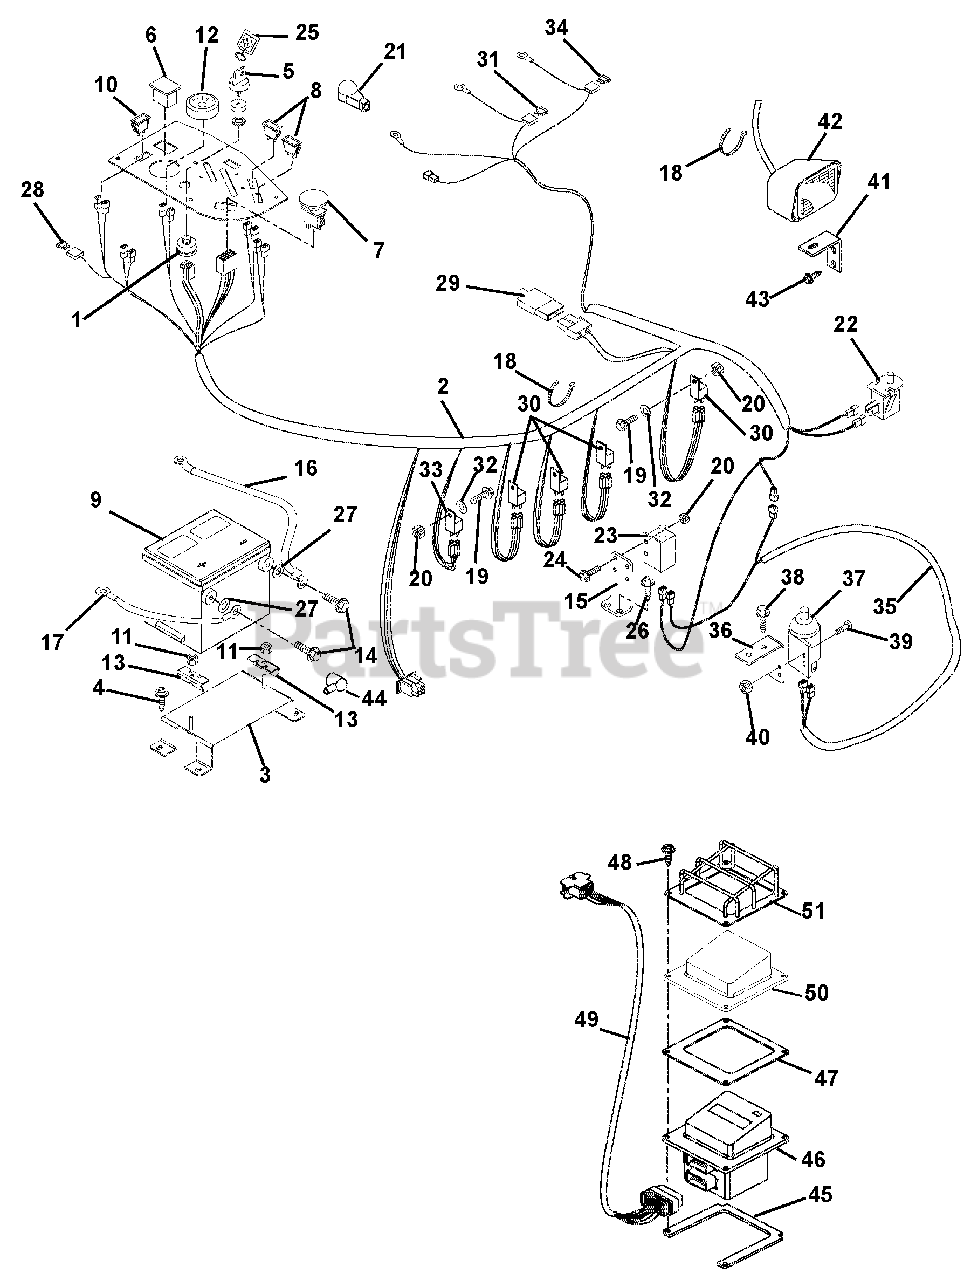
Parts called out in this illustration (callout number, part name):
1	Switch, Ignition (Diesel)
2	Harness, Wiring (Diesel)
3	Weldment, Battery Support
4	Screw-Tapping .38-16 x .75 Hex Washer Head
5	Key-with Cap
7	Switch-Clutch With Retainer Ring
8	Light-Indicator Kit
9	Battery with Tube
10	Switch, Light
11	Nut-Locking-Top-Flange .31-18
12	Gauge, Temperature
13	Bracket, Battery Hold-Down
14	Bolt-Hex .25-20 x .75 Grade 5
15	Mount, Safety Switch
16	Positive Cable
17	Cable, Negative Battery
18	Cable Tie
19	Screw-Machine 10-24 x .75 Hex Washer Head
20	Nut-Locking-Nylon 10-24 With Insert
21	Eyelet Terminal Boot
22	Switch, Snap Mounting (N.O.) (Included with Seat)
23	Switch-Single Pole
24	Screw-Machine 10-24 x .75 Hex Washer Head
25	Key Chain
26	Screw-Tapping .25-20 x .50 Hex Washer Head
27	Washer-Flat-Steel .406 x 1.00 x ..083
28	Fuse, 15 Amp
29	Diode, Connector Shell
30	Relay (Included with Harness)
31	Fuse, 30 Amp (Included with Harness)
32	Washer-Flat-Steel .25 x .562 x .049
34	Fuse, 50 AMP (Maxi Fuse) (Included with Harness)
35	Harness, Wire Adapter CE
36	Mount- Switch
37	Switch-Single Pole (N.O.) with Cover
38	Screw-Tapping .31-18 x .50 Hex Washer Head
39	Screw-Machine 10-24 x .75 Hex Washer Head
40	Nut-Locking-Nylon 10-24 with Insert
41	Bracket, Headlight Mounting
42	Headlight
43	Screw-Tapping .38-16 x .50 Hex Washer Head
44	Boot, Eyelet Terminal
45	Spacer, Enclosure Mounting (Bottom)
46	Assembly, Eye-Q
47	Gasket, Eye-Q
48	Screw, Machine 10-24 x 1.0 Slotted Pan Black
49	Harness Jumper (Eye-Q)
50	Guard, Element
51	Guard, Vinyl Eye-Q
